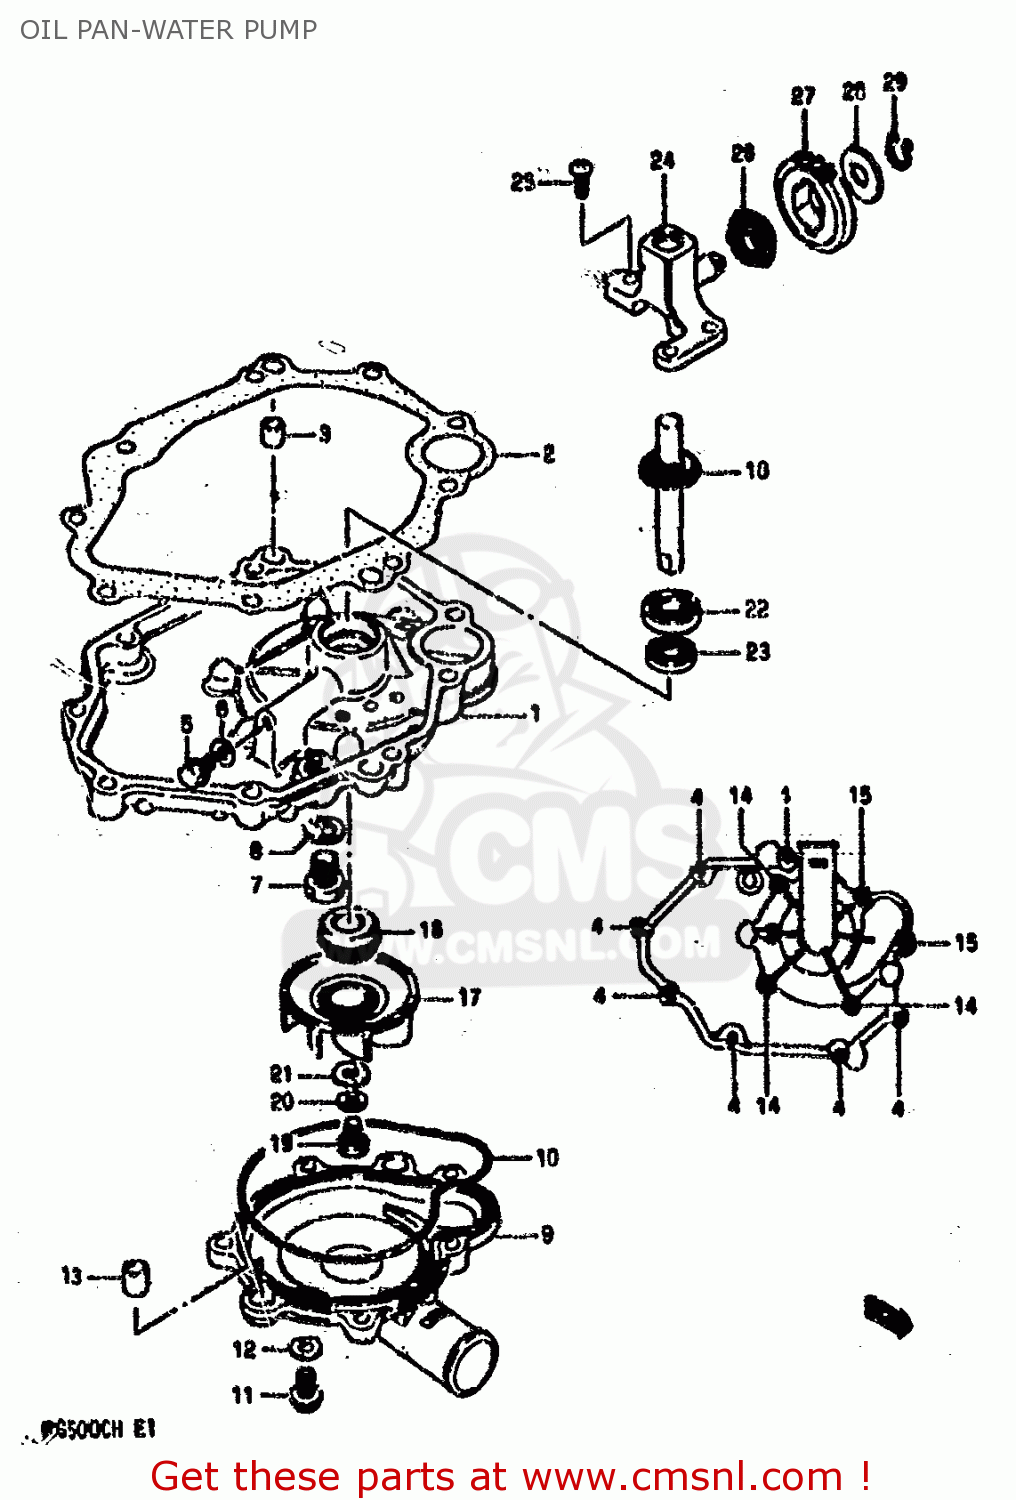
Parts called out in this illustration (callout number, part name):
1	PAN,OIL
2	GASKET,OIL PAN (MCA)
3	PIN
4	BOLT
5	BOLT
6	GASKET
7	PLUG
8	GASKET(10X14X3.6) (NAS)
9	CASE,WATER PUMP
10	O RING,WATER PUMP CASE
11	BOLT 6X12
12	GASKET(6.2X11X1).2 (NAS)
13	PIN
14	BOLT
15	BOLT
16	SEAL,WATER PUMP SHAFT
17	IMPELLER
18	SHAFT,WATER PUMP
19	BOLT(6X13)
20	WASHER
21	GASKET (NAS)
22	BEARING
23	SEAL,OIL(10X20X5)
24	HOUSING,WATER PUMP SHAFT
25	SCREW
26	BEVEL,WATER PUMP DRIVEN
27	GEAR,WATER PUMP DRIVEN
28	WASHER,DRIVE BEVEL
29	CIRCLIP
